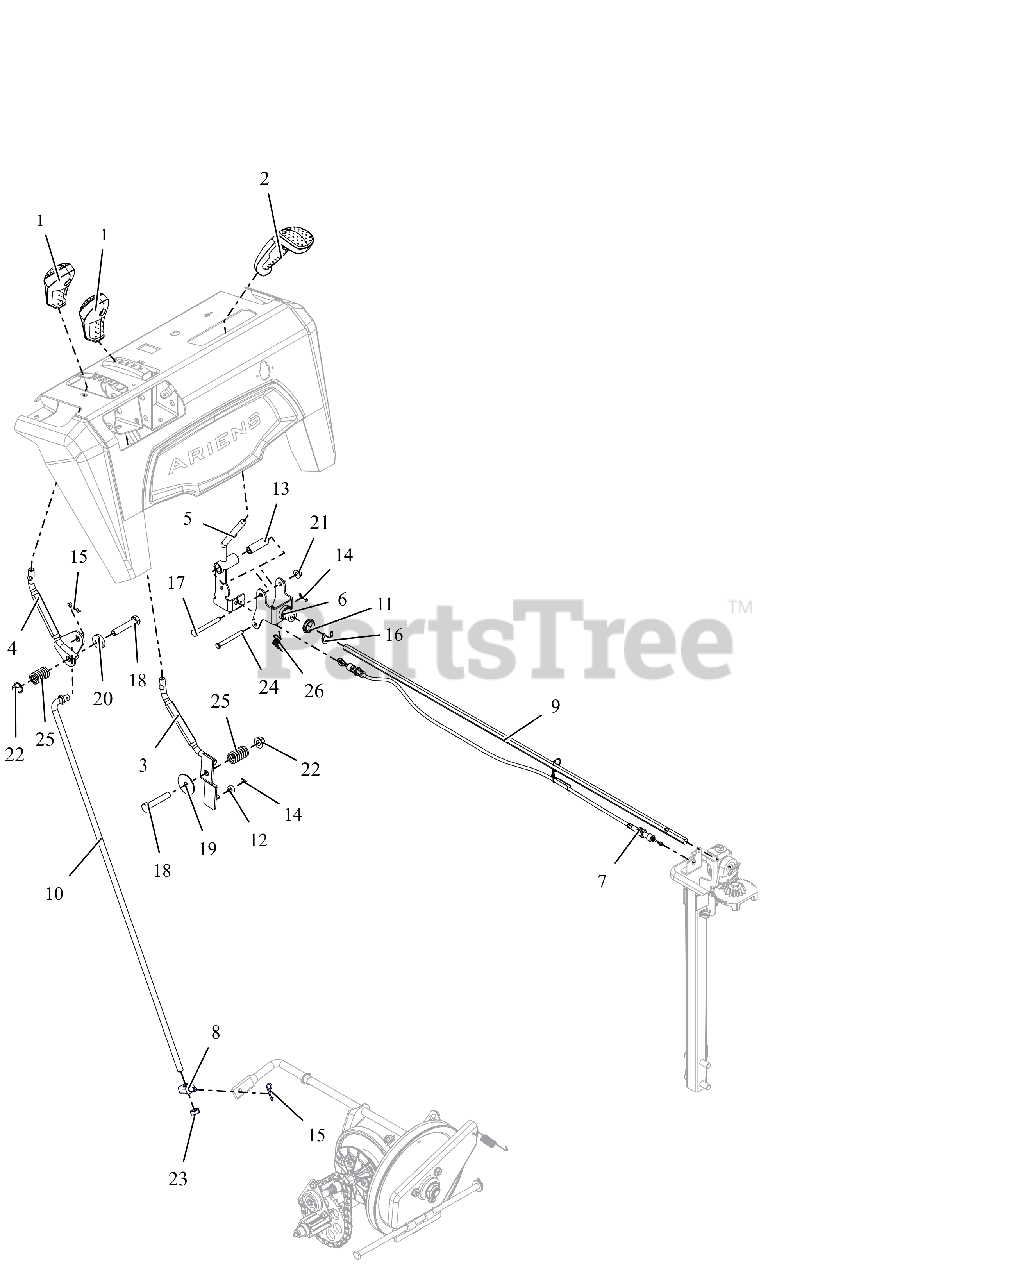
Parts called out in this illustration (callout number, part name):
1	KNOB, CONTROL, DASH
2	HANDLE, QUICK TURN, ASM
3	WELDMENT,LG DASH DEFL CONTROL
4	WELDMENT,LG DASH SPEED CONTROL
5	WELDMENT, CONTROL LEVER
6	WELDMENT, CONTROL BRACKET
7	CABLE, CHUTE LOCK, PRO
8	PIVOT,SHIFT ROD .375-16(TRUNN)
9	ROD, HEX - CHUTE ROTATION
10	ROD, SHIFT-PRO
11	BUSHING, POLYLINER-.75 SNAPIN
12	BSHG-SLV .265X.500X.219
13	BSHG, SLV .265X.505X1.665
14	PIN, HAIR #178 .06X.77 ZCC
15	PIN, HAIR #213 .08X1.19 ZCC
16	E-RING .750X.050
17	BLT,HEX .25-20X2.25 G5 ZCC
18	BLT,HEX .38-16X2.00 G5 ZCC
19	WSHR,FLT .380X1.50X.062 ZCC
20	WSHR, FLT .406X1.00X.188 ZCC
21	NUT-LK-CTR-FLG .25-20 ZC120
22	NUT-LK-TOP-FLG .38-16 ZC120
23	NUT-JAM .375-16 G2 ZCC
24	PIN, CLEVIS - .25 X 2.25 ZCC
25	SG-COMP .125X.781X1.250
26	SPRING-EXT .047X.438X1.45
